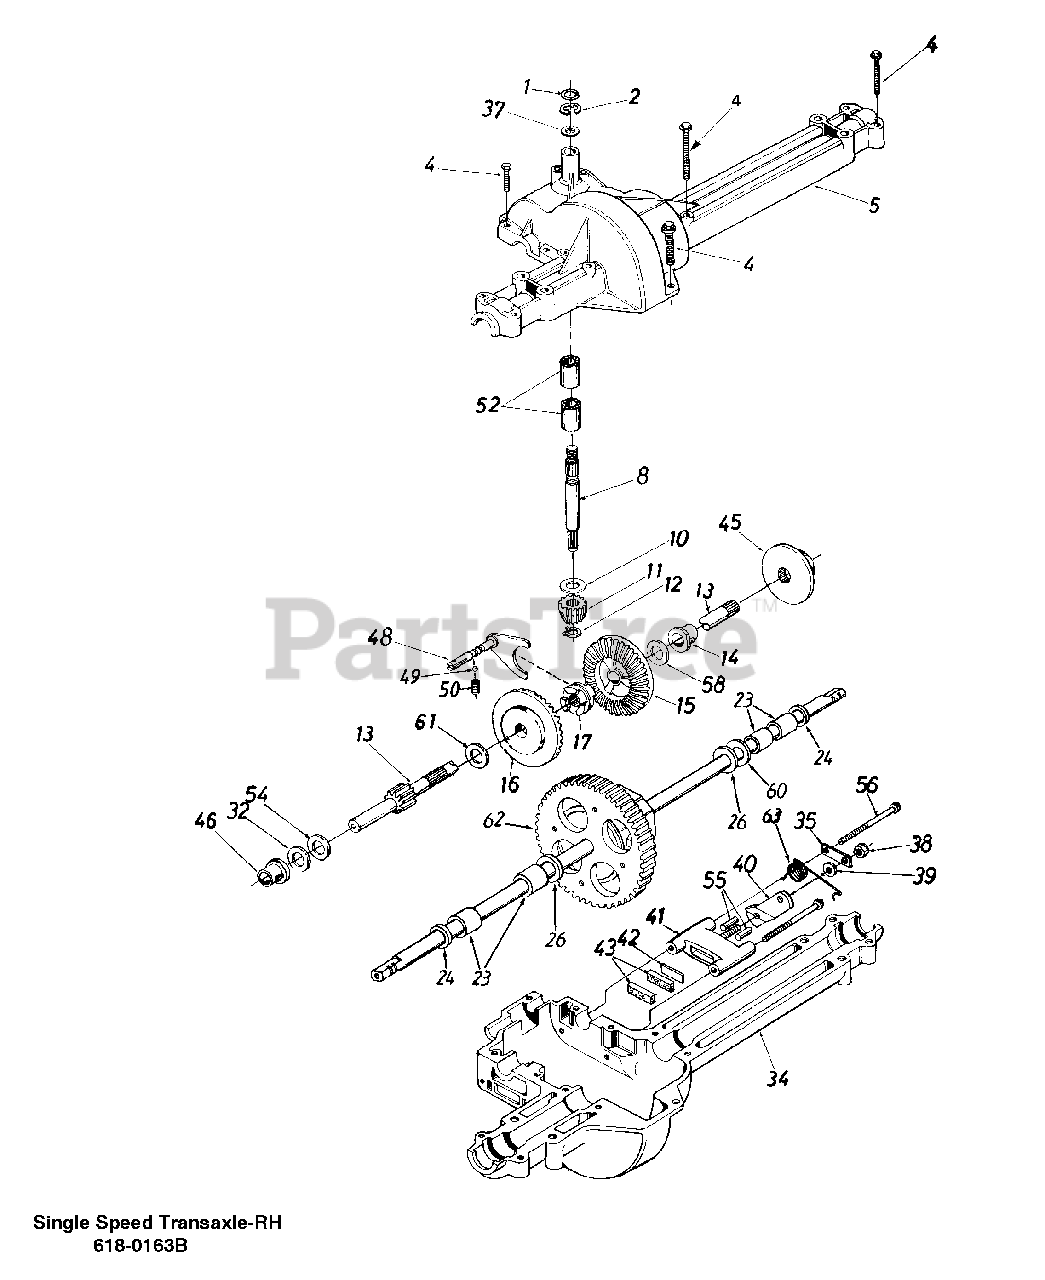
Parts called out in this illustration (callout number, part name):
4	Hex Tap Scr. 1/4-20 x 1.625 Lg.
5	Upper Housing
10	Thrust Washer 5/8" I.D. x 1.25" O.D.
11	Pinion Input 14T
12	Retaining Ring
13	Drive Shaft-R.H. Brake
14	Flange Brg. 5/8" I.D. x 3/4" Lg.
15	Bevel Gear 42T Small I.D.
16	Bevel Gear 42T Large I.D.
17	Clutch Collar
23	Sleeve Bearing 3/4" I.D. x 1.0" Lg.
24	Oil Seal 3/4" I.D.
26	Fl-Wash. .760" I.D. x 1.5" O.D.
32	Thrust Wash. 5/8" I.D. x 1" O.D. x .025" Thk.
34	Lower Housing
35	Anti-Rotation Brkt.
37	Fl-Wash. 5/8" I.D. x 1" O.D. x .020" Thk.
38	Hex Nut 5/16-24 Thd.
39	Fl-Wash. .344" I.D. x .875" O.D.
40	Actuating Arm
41	Brake Yoke
42	Puck Plate
43	Brake Puck
46	Flange Bearing 5/8" I.D. x 15/16" Lg.
48	Shift Fork Ass'y.
49	Ball Detent .250" Dia.
50	Spring Detent
52	Needle Brg. 5/8" I.D. x 1/2" Lg.
54	Fl-Wash. 5/8" I.D. x 1" O.D.x .020 Thk.
55	Actuating Pin 5/16" Dia.
56	Hex Wash Hd. Self-Tap Scr. 1/4-20 Thd.
58	Fl-Wash. 5/8" I.D. x 1" O.D. x .020 Thk.
60	Fl-Wash. .76" I.D. x 1.5" O.D. x .010" Thk.
61	Thrust Washer
62	Differential Ass'y.
63	R.H. Brake Spring
618-0163B	Single Speed Transaxle-RH
